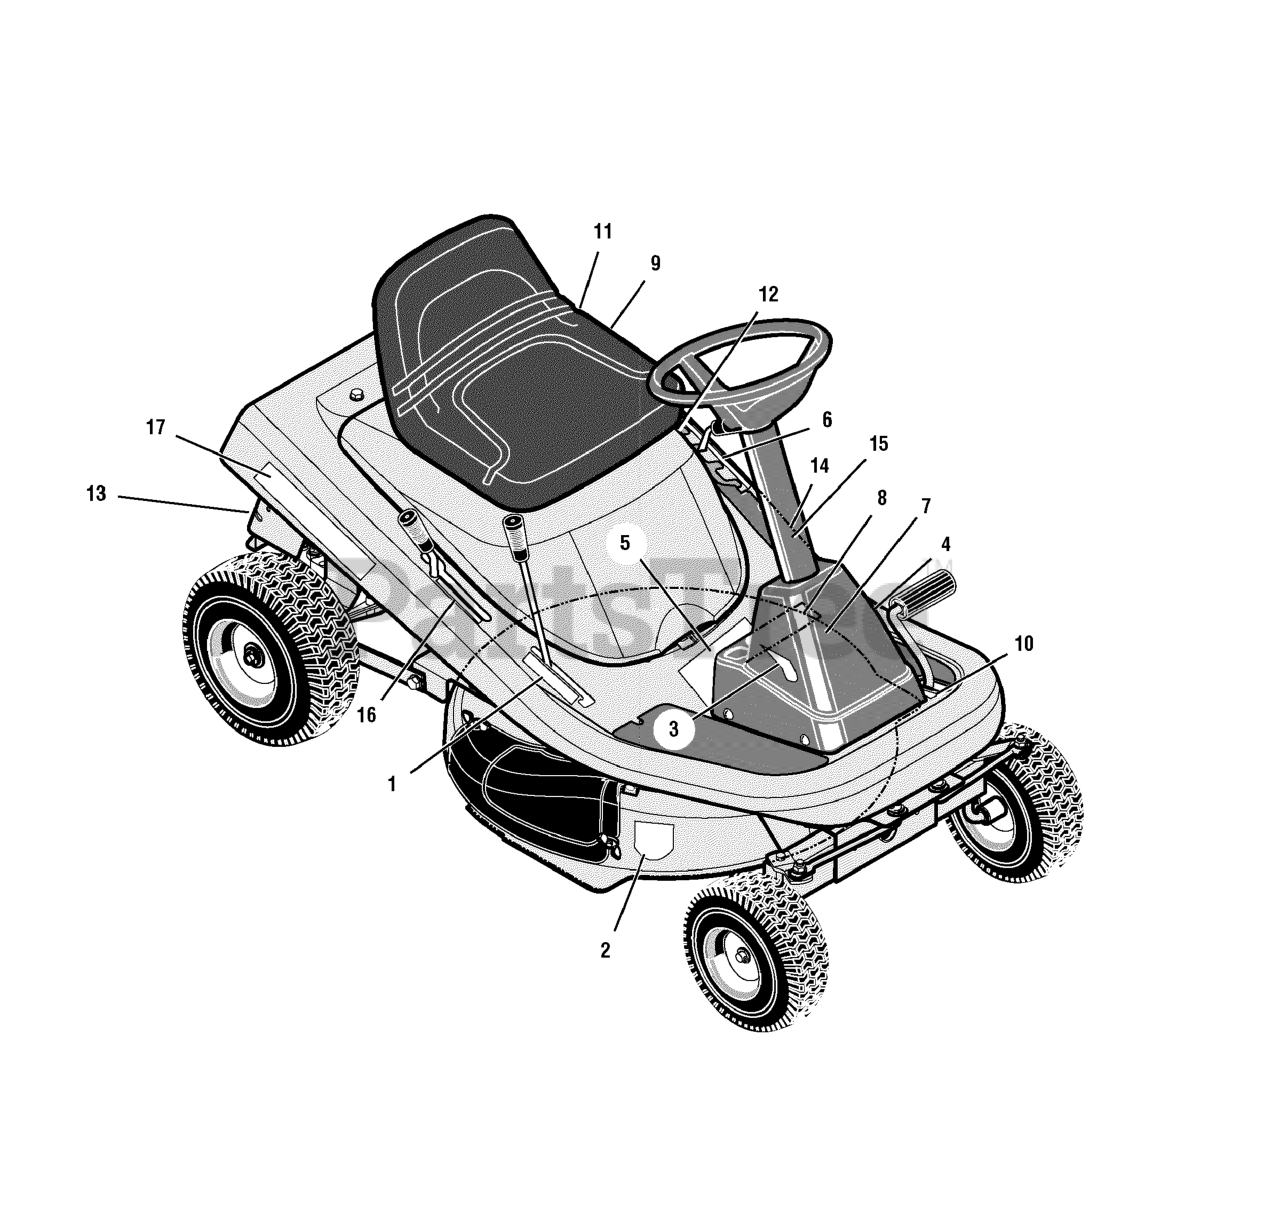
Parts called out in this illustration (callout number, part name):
1	DECAL, ENGAGMENT
2	DECAL, ENGLISH CUT FINGER
3	DECAL, 105/76 RH AUTO
4	DECAL, 105/76 LH AUTO
5	DECAL, WARNING CE
6	DECAL, HGT ADJUST 6 POS.
7	DECAL, NO STEP CE
8	DECAL, PARK BRAKE SYMBOL
9	DECAL, THOTTLE CONTROL
10	DECAL, CLUTCH/BRAKE XPT
11	DECAL, GAS GAUGE
12	DECAL, HEAT SHIELD WARNING
13	DECAL, DRAWBAR WARNING PICT
14	DECAL, WARNING-PINCH POINT
15	DECAL, DECK LEVEL
16	DECAL, GEAR SELECT 5 SPEED
17	DECAL, MASPORT RH & LH
